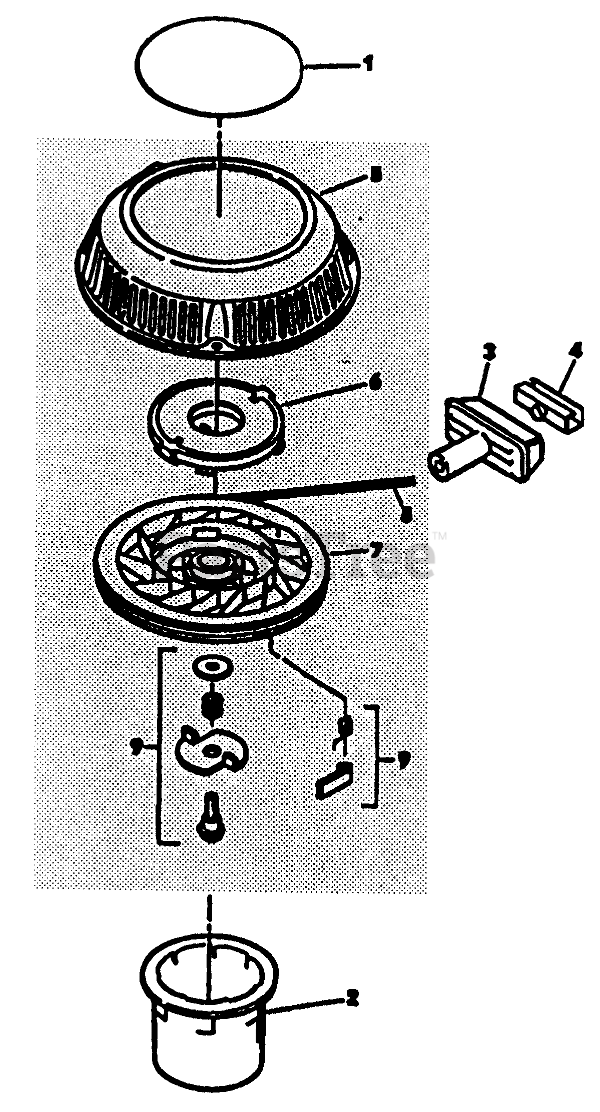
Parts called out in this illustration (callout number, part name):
1	DECAL-RECOIL S
2	HUB-STARTER E COMM.
3	HANDLE-START
4	CLIP-STARTER
5	STARTER HOUSING & SHAFT
6	Recoil Spring
7	PULLEY
8	ROPE-RECOIL
9	DOG KIT
